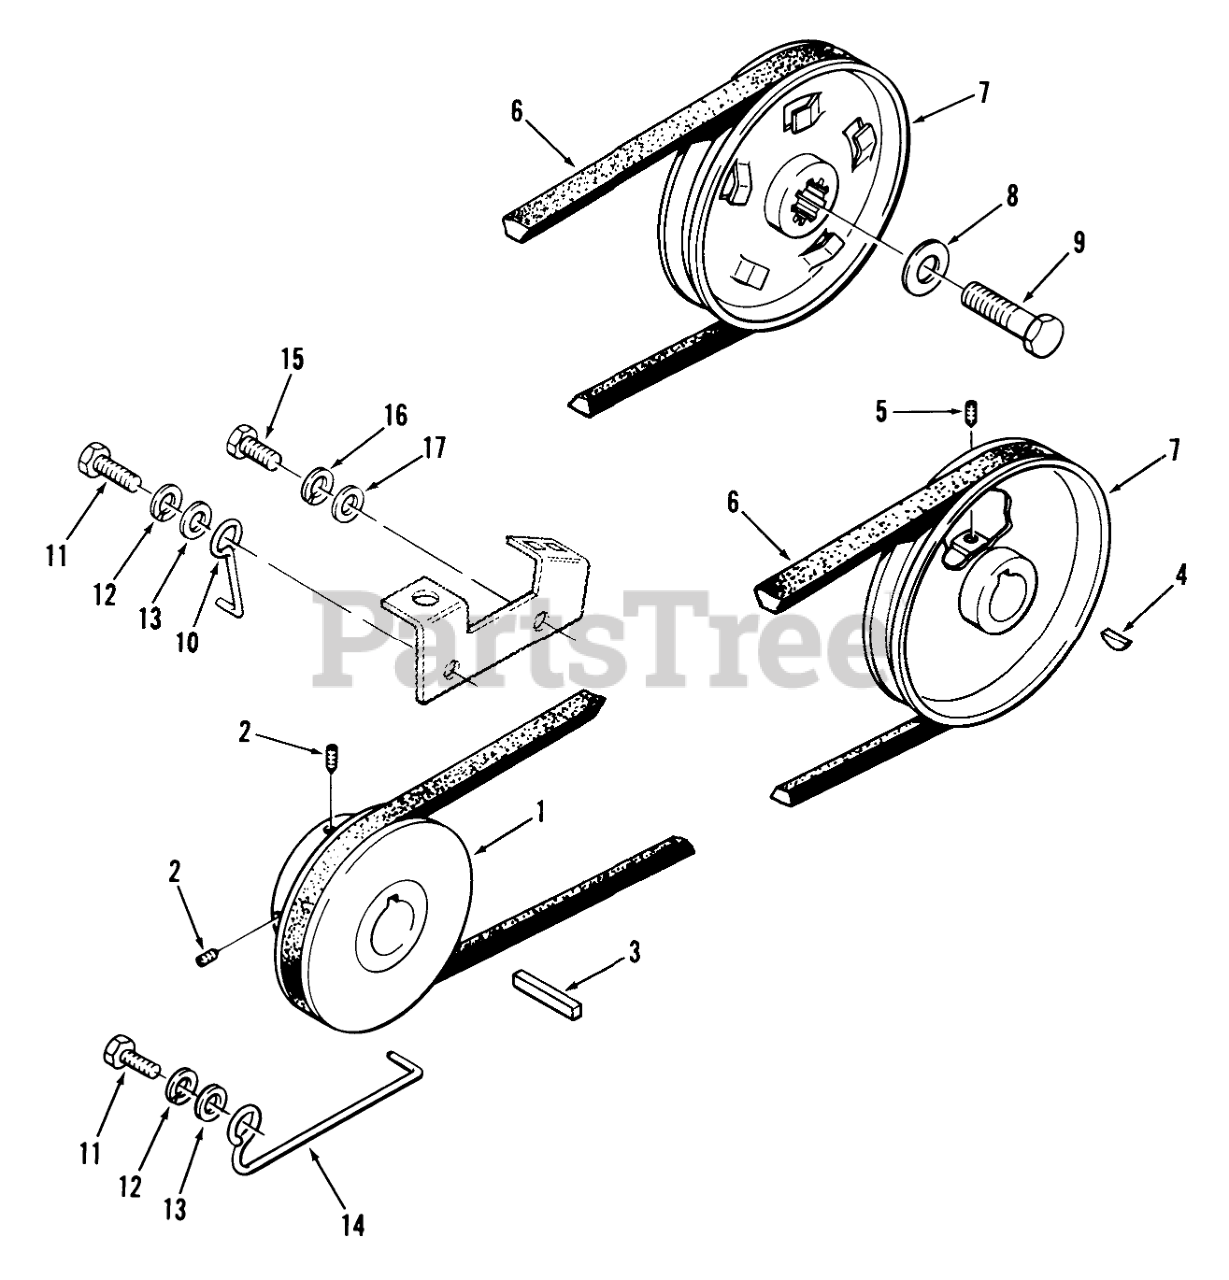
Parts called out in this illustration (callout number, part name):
1	PULLEY
2	Set Screw
4	KEY-HI PRO
5	Set Screw
6	V BELT
6	V-BELT
6	Belt-Drive
7	Transmission Drive Pulley
7	PULLEY-TRANSMISSION
8	WASHER
9	Bolt
10	Belt Guide-Top
11	7/16-14 x 1 1/4 Bolt
11	Bolt
12	LOCKWASHER
13	WASHER
13	Washer
14	Belt Guide-Bottom
